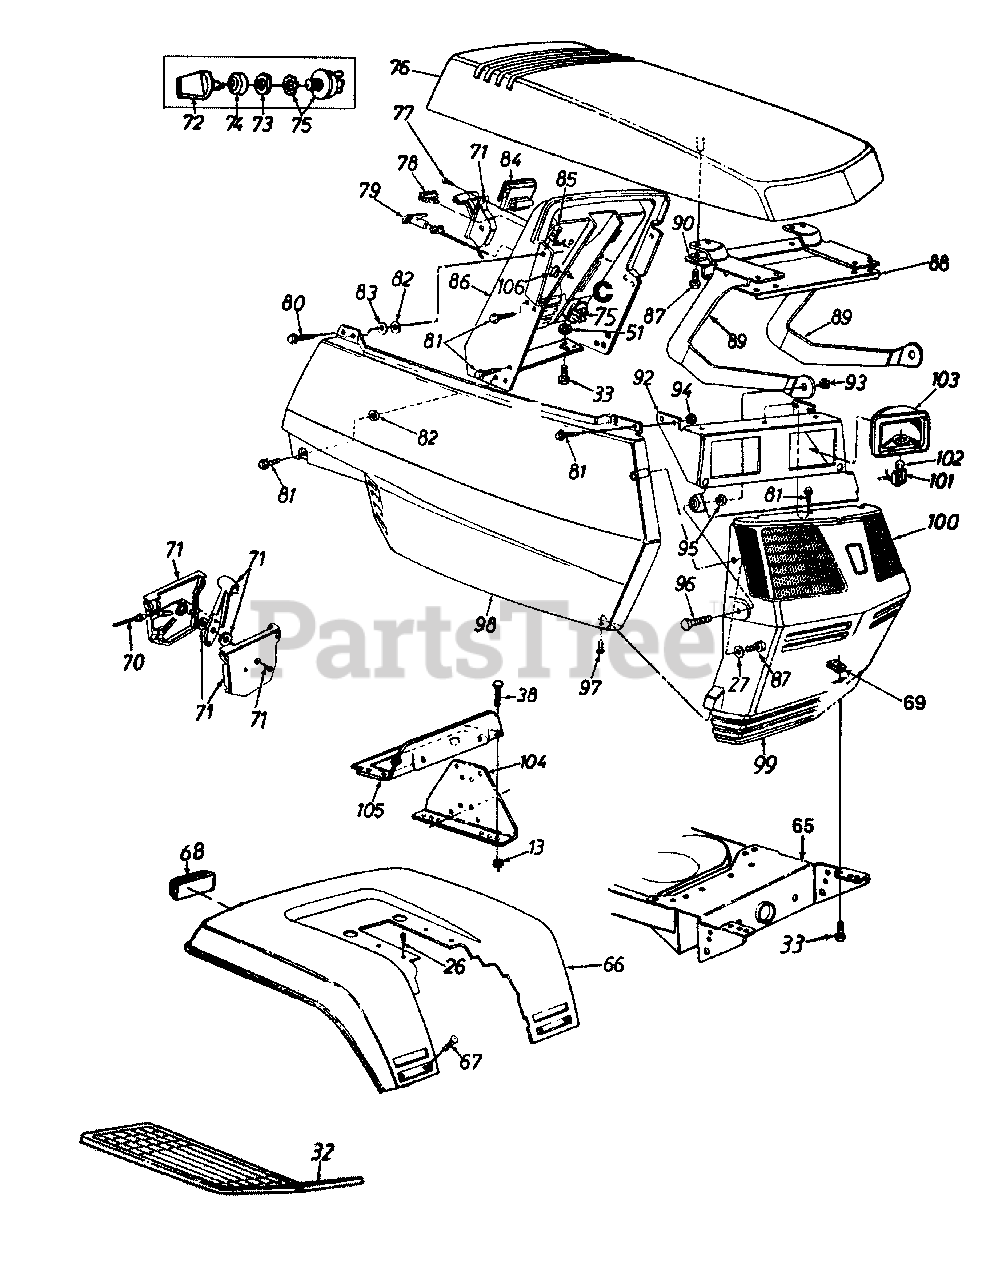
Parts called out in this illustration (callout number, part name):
13	Hex Sems Nut 1/4-20 Thd.
26	Hex Wash. Hd. AB-Tap Scr.5/16 x .75" Lg.
27	Fl-Wash..218" I.D. x .5" O.D.
32	Rubber Foot Pad-L.H.
33	Hex Bolt 5/16-18 x .75" Lg.
38	Hex Bolt 1/4-20 x .62" Lg.
51	Hex Sems Nut 5/16-18 Thd.
68	Reflector
69	U-Nut 5/16-18 Thd.
70	Throttle Wire 18.5" Lg.
71	Throttle Control Box Ass'y
72	Ignition Key
73	Ignition Switch Nut
74	Ignition Switch Cap
75	Ignition Switch
76	Hood
77	Truss Mach. AB-Tap Scr. #10 x .5" Lg.
78	Light Switch
79	Choke Control 29" Lg.
80	Hex Wash. Hd. Tap Scr. 1/4 x .75" Lg.
81	Hex Tap Scr. 1/4-20 x .5" Lg.
82	Push Nut Fastener
83	Fl-Wash..27" I.D, x .948"
84	Ammeter
85	Speed Nut 1/4-20 Thd.
86	Dash Panel
87	Hex Wash. Hd. B-Tap Scr.l/4 x ,75" Lg,
94	Hex L-Nut 1/4-20 Thd.
95	Hex Jam Nut 5/16-18 Thd.
96	Hex Bolt 5/16-18 x 7/8" Lg.
97	Truss Mach. B-Tap Scr. #10 x ,5" Lg.
98	Side Cover-R.H.
99	Grille
100	Lens-L.H.
101	Twin Lock-Lamp Socket
102	Lamp
103	Headlight Housing
